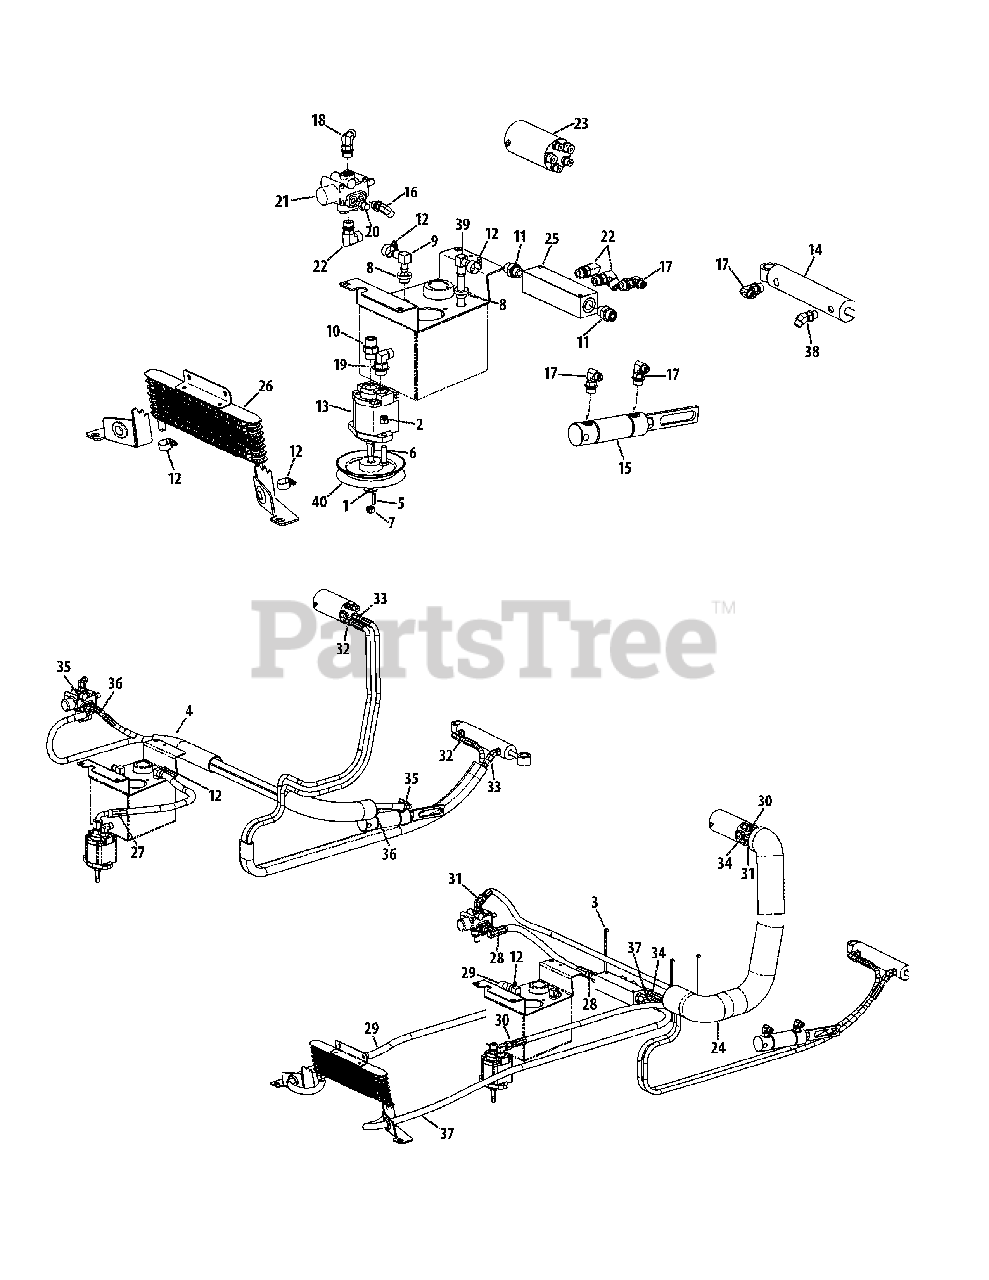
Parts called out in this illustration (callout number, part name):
1	Washer, .438 x 1.00 x .078
2	Nylock Nut, 3/8-16
3	Cable Tie
4	Reel Return Line Sleeve, 1.59
5	Key, .188 x .188 x .875
6	Hex Screw, 3/8-16 x 1.25
7	Counterlock Nut, 3/8-24
8	Grommet, .54 x .78
9	Elbow Fitting, 5/8 x 1/2
10	Hydro Adapter, 8 x 10
11	Hydro Adapter, 8 x 8
12	Hose Clamp
13	Gear Pump, 3.0
14	Steering Cylinder
15	Hydro Cylinder, 1.50 x 2.75
16	Elbow Fitting, 40RB-40RS
17	Elbow Fitting, 40RS-60RB
18	Elbow Fitting, 60RB-60RS
19	Elbow Fitting, 60RS-80RB
20	Fitting, 40RB-40RS
21	Dual Action Lift Hydro Valve
22	Elbow Fitting
23	Hydro Steering Valve
24	Anti-Abrasion Sleeve
25	Hydro Manifold, 8 x 6
26	Oil Radiator
27	Hose Assy. (Tank-Pump)
28	Hose Assy. (Lift Valve-Manifold)
29	Hose Assy. (Exchanger-Tank)
30	Steering Valve Pump Hose Assy.
31	Lift Valve Steering Valve Hose Assy.
32	Steering Ext. Steering Valve Hose Assy.
33	Steering Retractor Steering Valve Hose Assy.
34	Manifold Steering Valve Hose Assy.
35	Cylinder Retractor Lift Valve Hose Assy.
36	Cylinder Extension Lift Valve Hose Assy.
37	Exchanger Manifold Hose Assy.
38	Elbow Fitting
39	Elbow, 1/2 x 5/8
